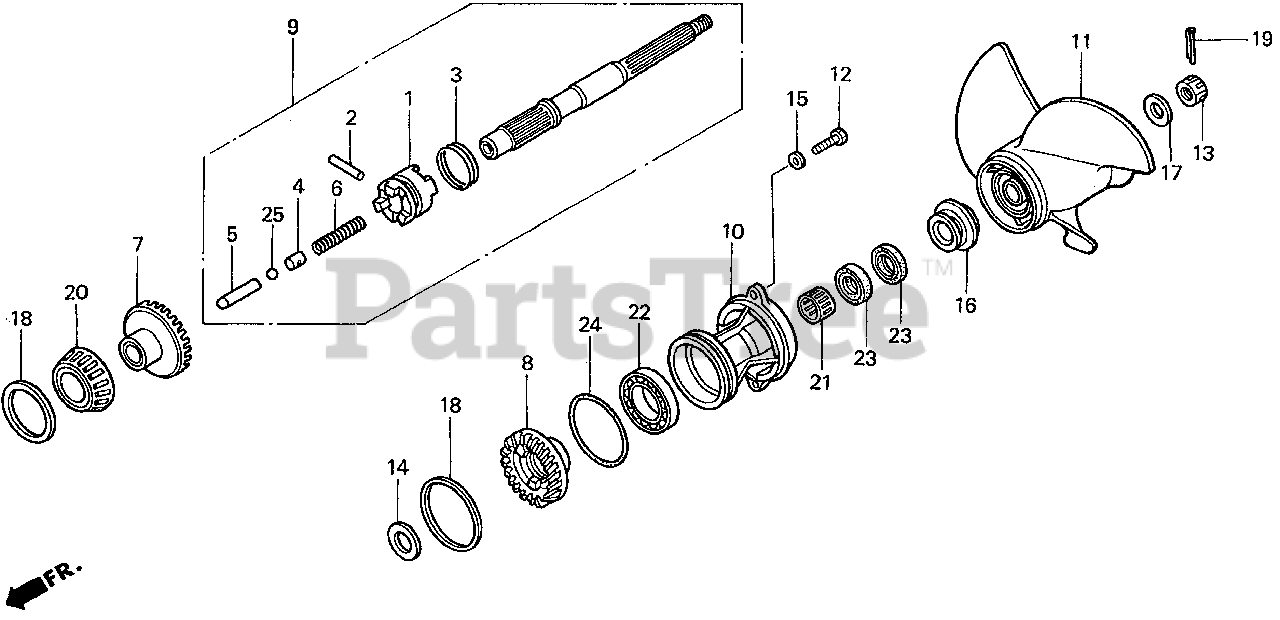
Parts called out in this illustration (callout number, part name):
1	SHIFTER, CLUTCH
2	PIN, SHIFTER
3	RING, CROSS PIN
4	HOLDER, SHIFTER PIN
5	SLIDER, SHIFT
6	SPRING, SHIFT
7	GEAR, FR. BEVEL
8	GEAR, RR. BEVEL
9	SHAFT ASSY., PROPELLER
10	HOLDER, PROPELLER
11	PROPELLER, THREE-BLADE (9-1/4X12) *NH283* (STIN GRAY)
11	PROPELLER, THREE-BLADE (9-3/4X9-7/8) *NH283* (STIN GRAY)
11	PROPELLER *NH283* (STIN GRAY)
12	BOLT, HEX. (6X20)
13	NUT, CASTLE
14	WASHER (22MM)
15	WASHER, PLAIN (6MM)
16	WASHER, PROPELLER THRUST
18	SHIM, FR. BEVEL (51X57X0.10) (A)
18	SHIM, FR. BEVEL (51X57X0.15) (B)
18	SHIM, FR. BEVEL (51X57X0.30) (C)
18	SHIM, FR. BEVEL (51X57X0.50) (D)
19	PIN, COTTER
20	BEARING (32X58X17)
21	BEARING, NEEDLE (22X28X20)
22	BEARING, RADIAL BALL (32X58X13) (KOYO)
23	SEAL, WATER (22X35X7)
24	O-RING (64X3)
25	BALL, STEEL (#11) (11/32)
